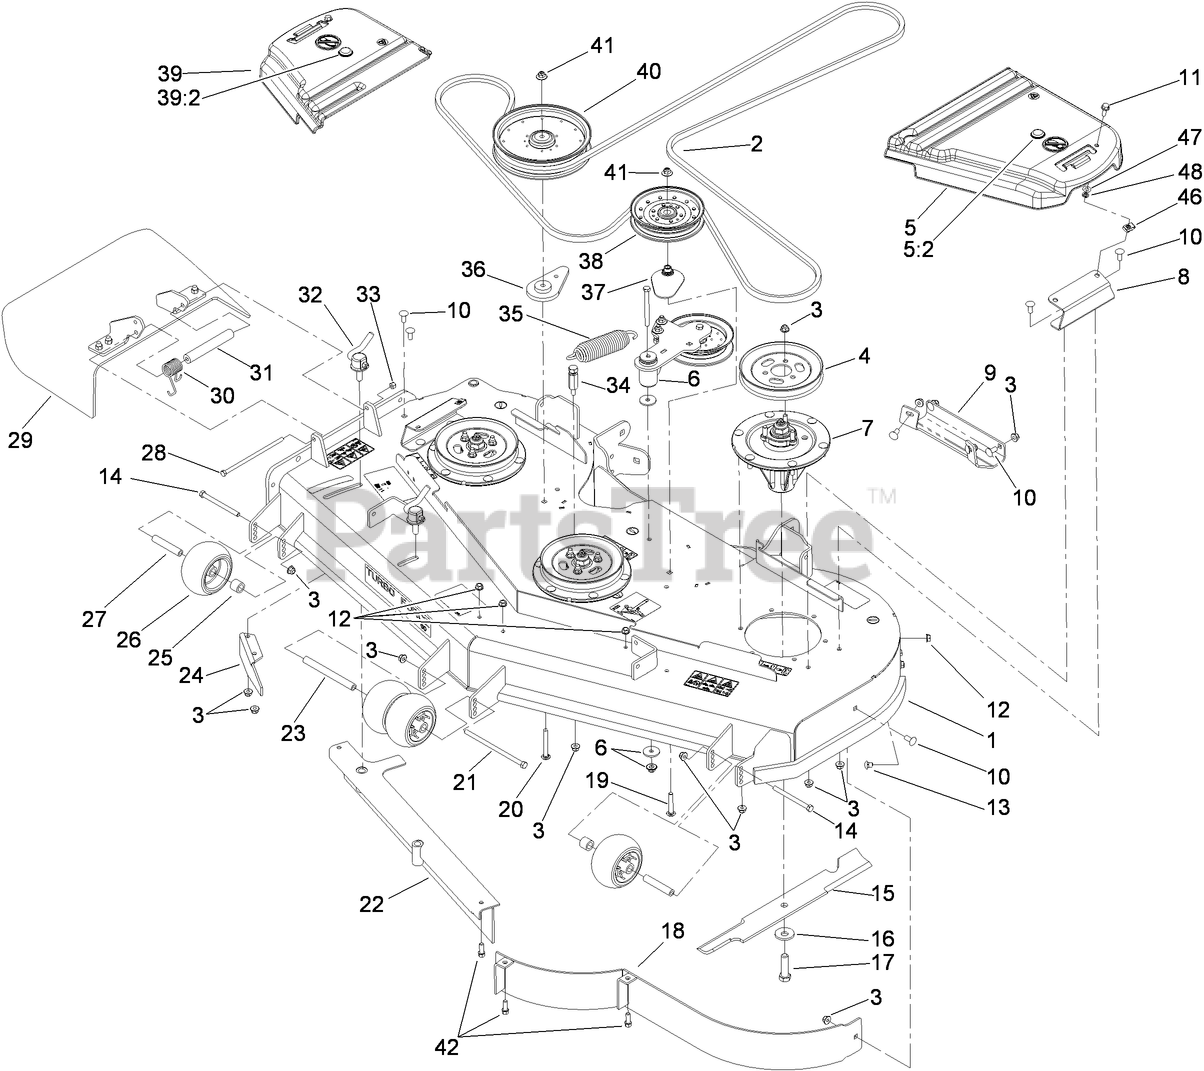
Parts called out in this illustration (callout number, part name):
1	DECK DECAL ASM
2	BELT-V
3	NUT-HF, NI
4	Pulley
5	LH BELT COVER ASM
5:2	PLUG-PLASTIC
6	IDLER ARM ASM
7	SPINDLE ASM
8	BRACKET-COVER, BELT
9	Plate-Skid
10	SCREW-CARR
11	SCREW-HHF
12	NUT-HHF, WHIZ
13	SCREW-CARR
14	SCREW-HH
15	BLADE-HI FLOW
16	Washer-Blade Bolt, Heavy
17	SCREW-BLADE
19	BOLT-CARR, SHORT NECK
20	SCREW-CARR
21	SCREW-HH
23	SPACER-WHEEL
24	BAFFLE-DISCHARGE
25	TUBE-SPACER
26	ROLLER-SCALP, ANTI
27	TUBE-SPANNER
28	SCREW-HH
29	RUBBER DEFLECTOR ASM
30	SPRING-TORSION
31	SPACER
32	LEVER ASM
33	NUT-LOCK, NI
34	ANCHOR-SPRING, TALL
35	EXTENSION-SPRING
36	SPACER-IDLER
37	SPACER-PULLEY
38	PULLEY-IDLER, FLAT
39	RH BELT COVER ASM
39:2	PLUG-PLASTIC
40	PULLEY-IDLER
41	NUT-FLANGE, NI
42	SCREW-HWH
46	NUT-U
47	WASHER-THRUST
48	NUT-PUSH
